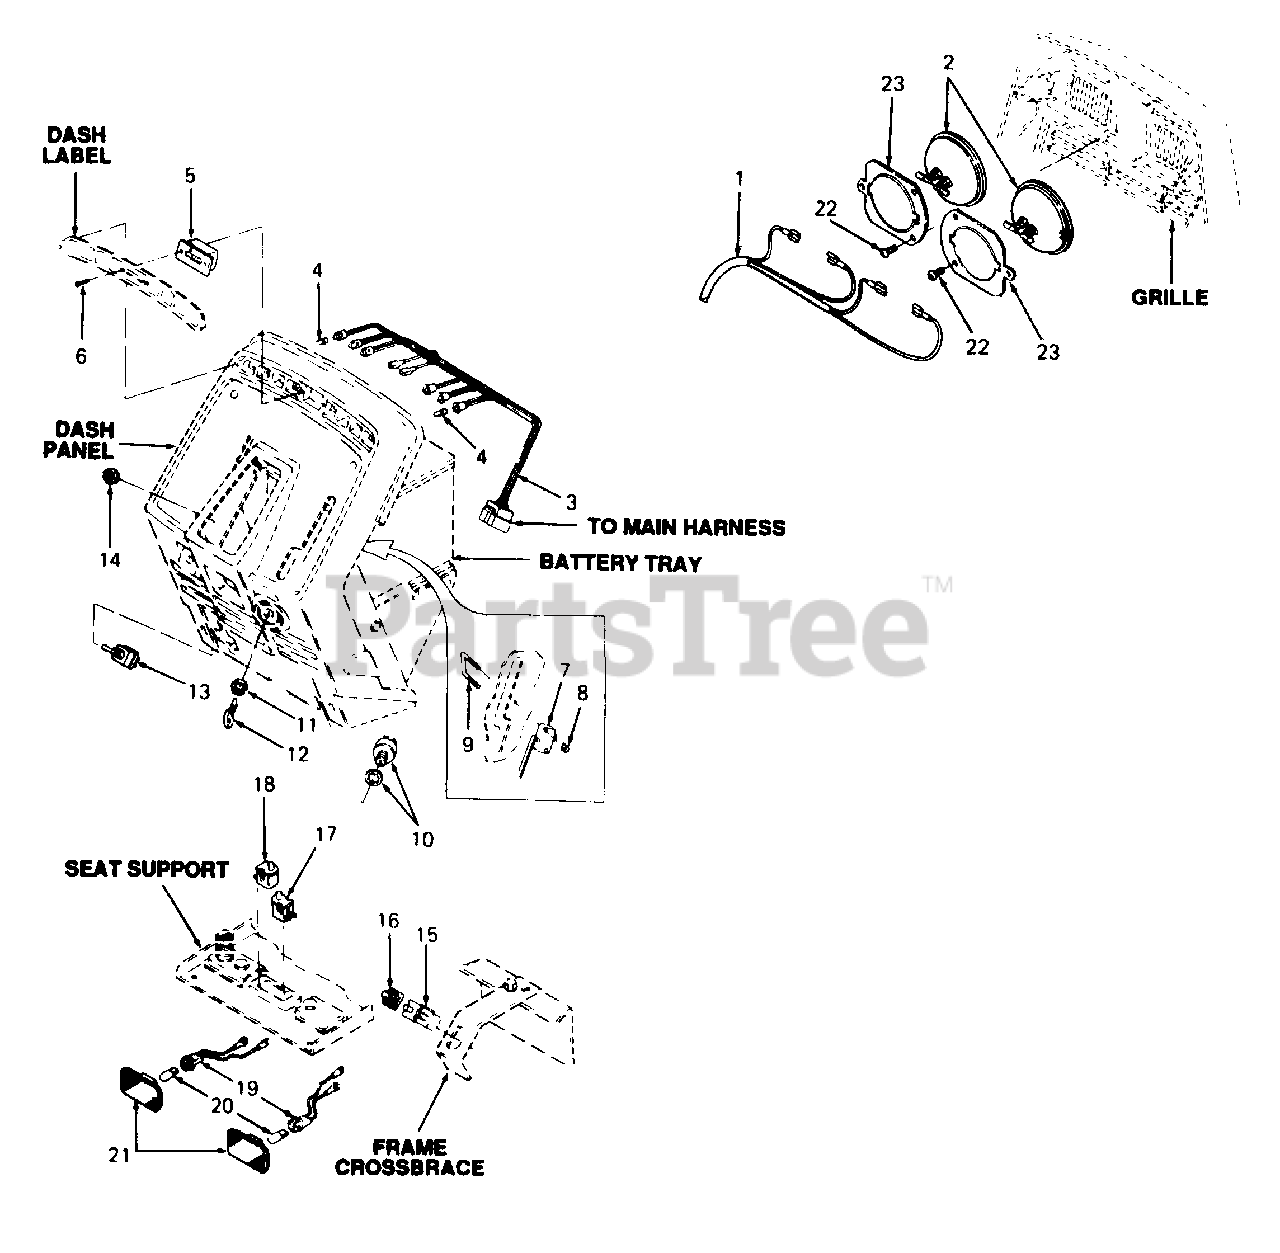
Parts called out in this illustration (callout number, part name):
1	Harness, Main Wire
2	Headlamp, Sealed Beam
3	Harness, Indicator Wire
4	Bulb, Indicator
5	Hour Meter
6	Screw, Truss Hd Tapp, #6 x .62 Lg
7	Switch, Reverse
8	Nut, Hex Insert Lock, #4-40
9	Screw, Switch
10	Switch, Ignition
11	Nut, Ignition Switch
12	Key, Ignition
13	Switch, PTO
14	Nut, Hex, 1/2-27 x .100 Thk
15	Switch, Interlock
16	Boot, Switch
17	Switch, Snap Mount - Normally Closed (Grey)
18	Switch, Snap Mount - Normally Open (Black)
19	Cable Assy, Tail Light
20	Bulb, Tail Light
21	Lens Assy, Tail Light
22	Screw, Pan Hd Tapp, #12 x .50 Lg
